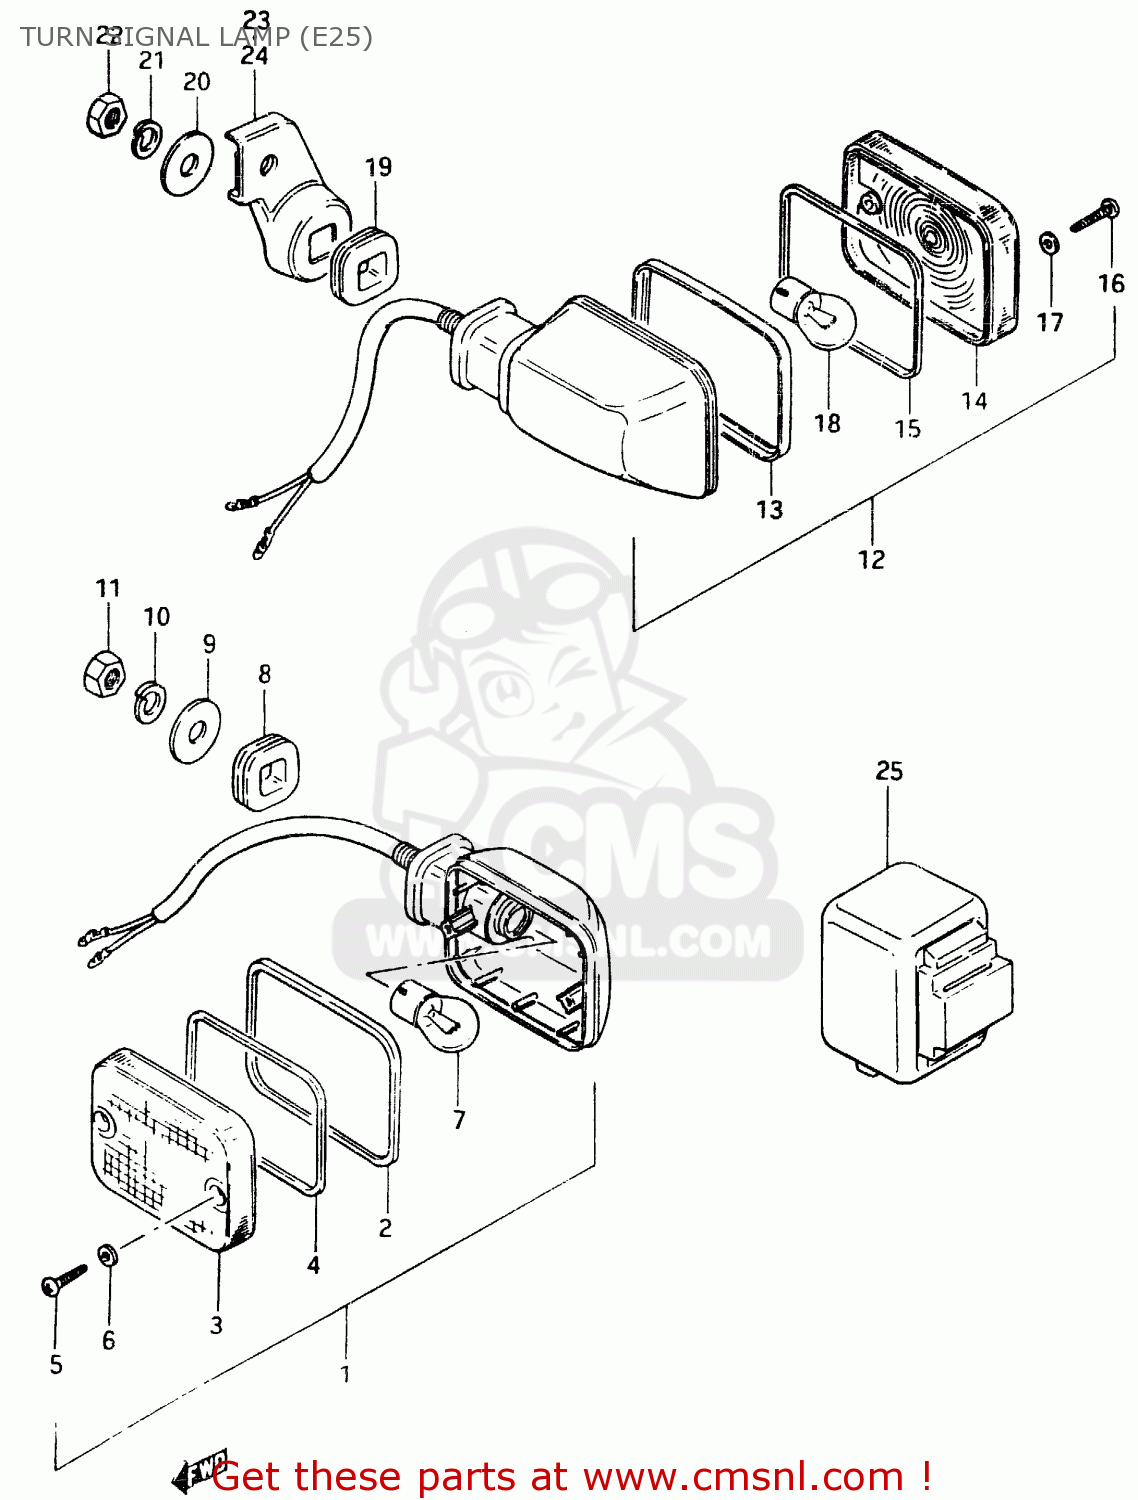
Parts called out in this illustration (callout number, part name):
1	LAMP ASSY,FR T
2	RIM
3	LENS
4	GASKET (NAS)
5	SCREW
6	GASKET (NAS)
7	BULB(12V21W)
8	CUSHION
9	WASHER (10.5X30X2.3)
10	LOCK WASHER
11	NUT
12	LAMP ASSY,RR T
13	RIM
14	LENS
15	GASKET (NAS)
16	SCREW
17	GASKET (NAS)
18	BULB(12V21W)
19	CUSHION
20	WASHER (10.5X30X2.3)
21	LOCK WASHER
22	NUT
23	BRACKET,REAR TURN SIGNAL
24	BRACKET,REAR TURN SIGNAL
25	RELAY, TURN SIGNAL
